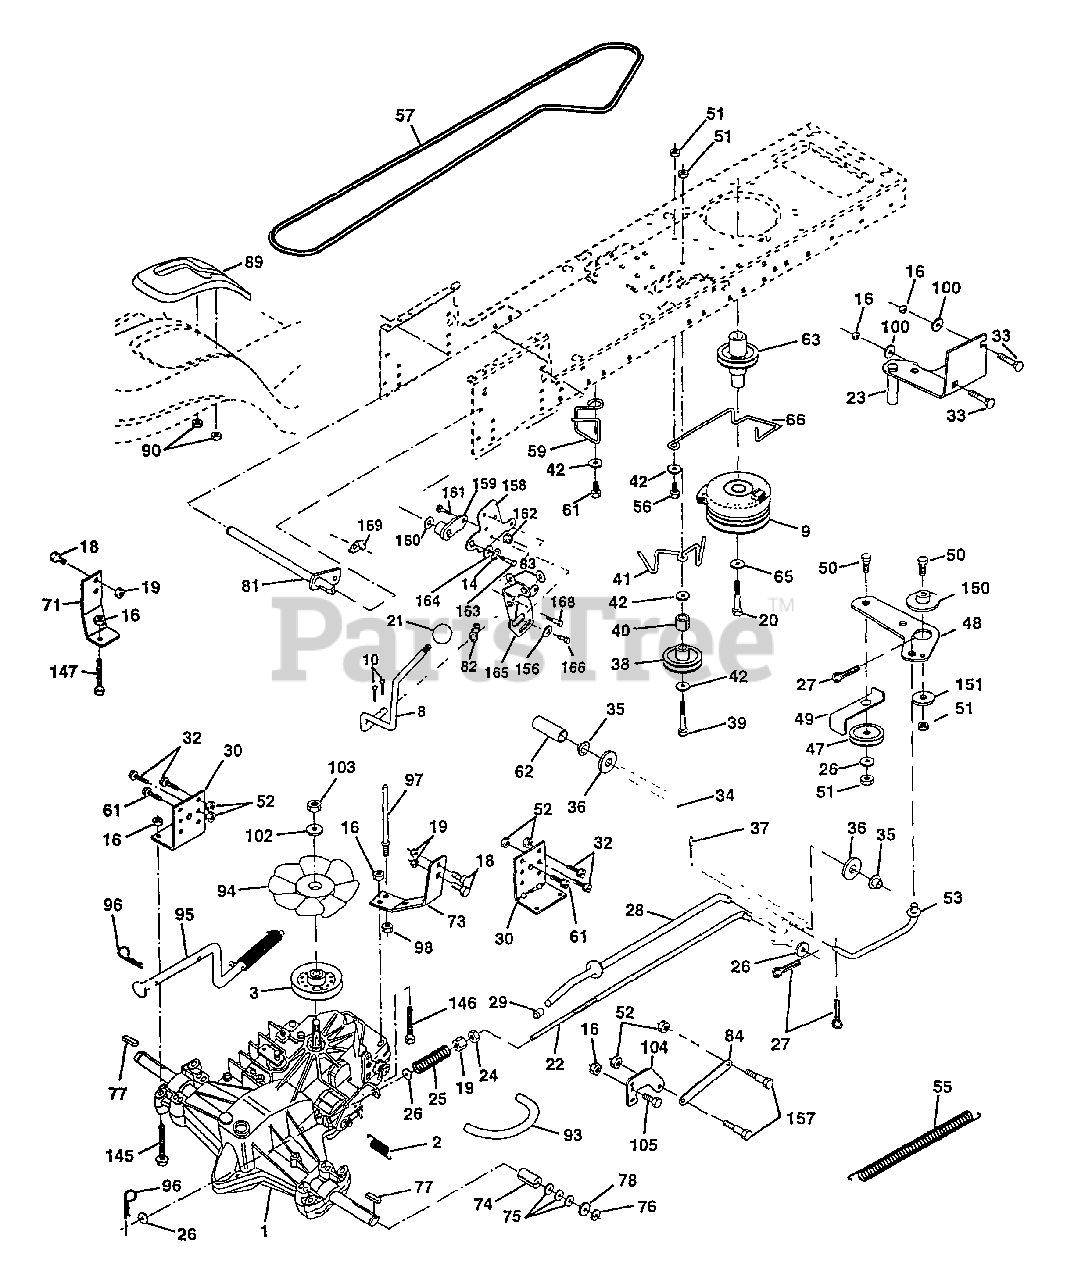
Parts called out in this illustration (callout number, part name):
1	Transaxle
2	Spring, Return, Brake
3	Pulley, Hydro 0650 LT/CRD
8	Rod Shift
9	Clutch Electric
10	Pin Cotter 1/8 x 1 CAD
14	Washer Lock Hvy. Helical
16	Nut Lock Hex W/Ins 5/16-18 Unc P
18	Bolt Fin Hex 3/8-16 Unc x 1 Gr. 5
19	Nut Lock Hex W/Wsh 3/8-16 Unc
20	Bolt Hex 7/16-20 x 4-1/4 Ga. 5
21	Knob, Deluxe 1/2-13
22	Rod, Brake Hydro
23	Bracket Asm Mtg Cl
24	Nut
25	Spring, Brake Rod
26	Washer
27	Pin Cotter 1/8 x 3/4 CAD.
28	Rod, Parking Brake
29	Cap, Parking Brake
30	Bracket, Transaxle
32	Bolt Hex Hd 5/16-18 Unc x 3/4
33	Bolt 5/16-18 x 3/4
34	Shaft, Foot Pedal
35	Bearing, Nylon
36	Washer
37	Pin, Roll
38	Pulley, Idler, Flat
39	Bolt
40	Spacer, Split
41	Keeper, Belt Retainer
42	Washer 13/32 x 13/16 x 12 Gauge
47	Pulley, idler, V-Groove
48	Bellcrank Clutch Grnd Drv STL
49	Retainer, Belt
50	Bolt
51	Nut Crownlock 3/8-16 UNC
52	Nut Crownlock 5/16-18 UNC
53	Link, Clutch
55	Spring, Return, Clutch
56	Bolt Fin Hex 3/8-16 UNC x 1-1/4
57	V-Belt, Ground Drive
59	Keeper, Center Span
61	Screw Thdrol. 3/8-16 x 3/4 Ty. TT
62	Cover, Pedal
63	Pulley, Engine
64	Bolt, Hex
65	Washer
66	Keeper Belt Engine
71	Strap Torque Lh Hydro
73	Strap Torque Rh Hydro
74	Spacer, Split
75	Washer 25/32 x 1-1/4 x 16 Gauge
76	E-Ring
77	Key, Square
78	Washer 25/32 x 1-5/8 x 16 Gauge
81	Shaft Asm. Cross
82	Spring Torsion
84	Link, Transaxle
89	Console, Shift
90	Nut Self Thd Wsh-Hd 1/4 Zinc
93	Line Fuel Hydro 4"
94	Fan, Hydro 7"
95	Control Asm Bypass Hydro
96	Retainer Spring 1" Zinc/Cad
97	Keeper Belt Rh Hydro 0750. 18/20"
98	Nut Keps Hex 3/8-16 Unc
100	Washer 11/32 x 3/4 x 16 Ga.
102	Washer Beliville .501D x 1.50D
103	Nut, Hex, Jam Toplock 1/2-20 UNF
104	Arm, Control Hydro
105	Screw Cap Hex 5/16 x 18 x 1
145	Bolt, Hex FLGHD 5/16-18 Gr. 5
146	Bolt Hex Flghd 5/16-18 x 2-1/4
147	Bolt Hex Flghd 5/16-18 x 1-1/2
150	Bushing Bellcrank Grd Drive
151	Washer 13/32 x 2 x 10 Ga.
156	Washer Srrted 5/16 ID x 1 x .125
157	Bolt shoulder 5/16-18 UNC-2a
158	Bracket Shift Mount
159	Hub Tapered Flange Shift LT
160	Washer 29/32 x 1-1/4 x 16 Ga.
161	Bolt Rdhd Sqnk 1/4-20 x 3/4 Gr. 5
162	Nut Crownlock 1/4-20 Unc
163	Bolt Hex Fin 1/4-20 Unc x 1 Gr. 5
164	Washer 5/8 x .281 x 10 Ga.
166	Screw 5/16-18 x 5/8
167	Washer 17/32 x 3/4 x 16 Ga.
168	Bolt Shoulder 5/16-18 x .561
169	Plate Fastening LT
